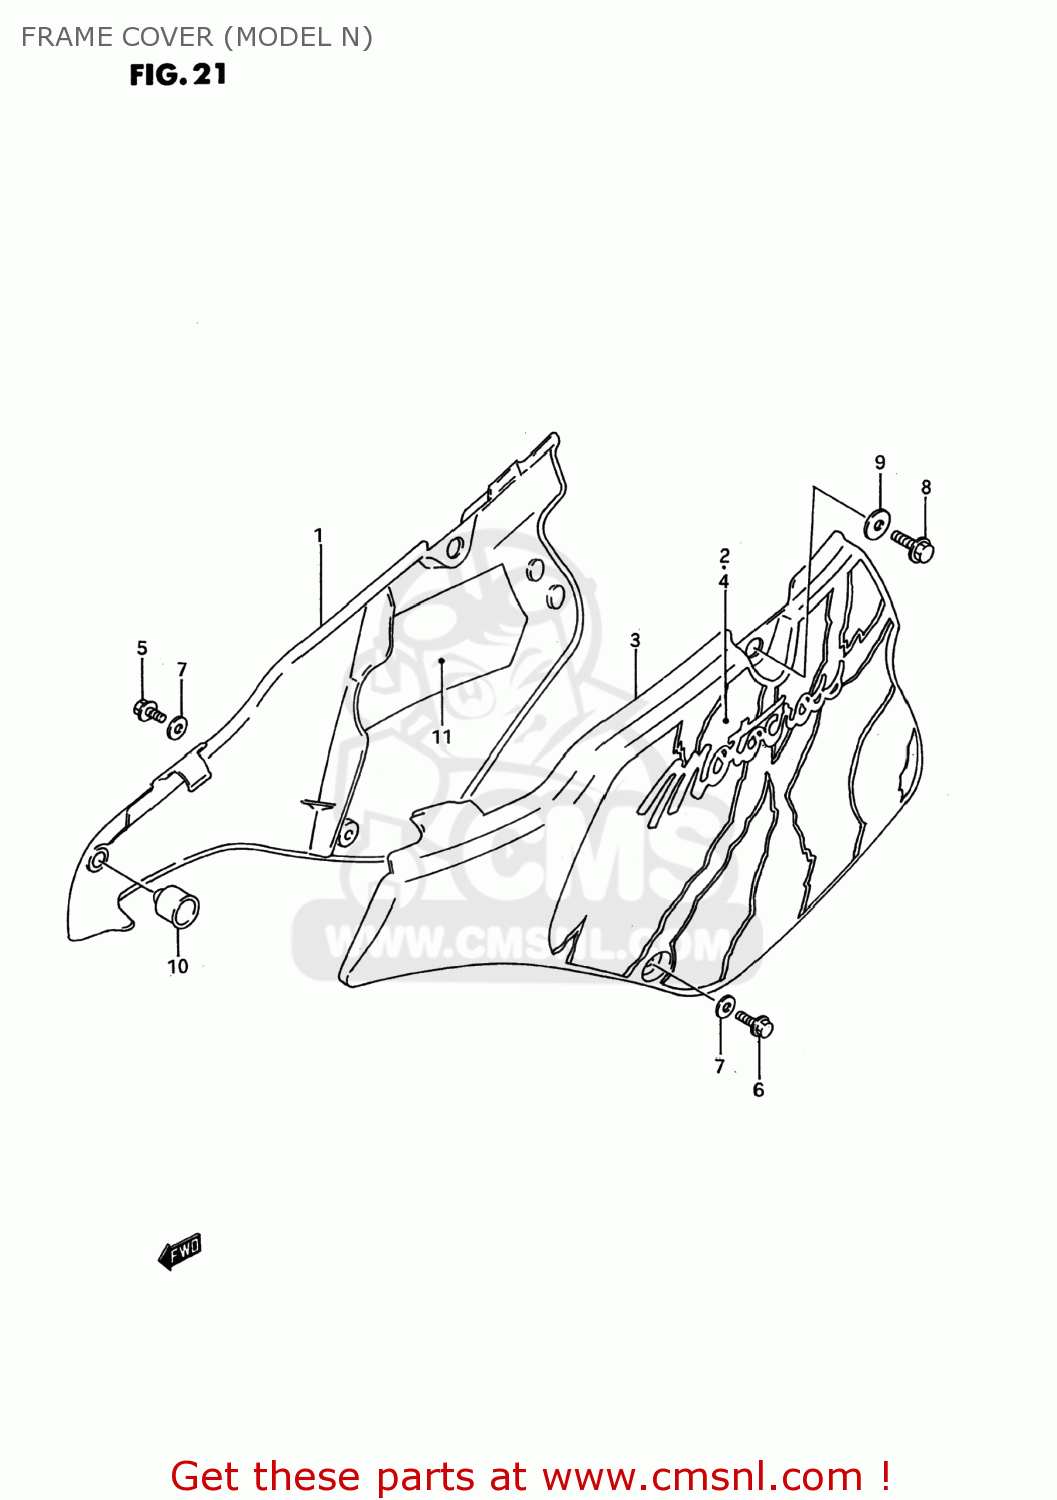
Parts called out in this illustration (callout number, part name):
1	COVER,FRAME,R(WHITE)
2	EMBLEM,FRAME COVER,RIGHT
3	COVER,FRAME,L(WHITE)
4	EMBLEM,FRAME COVER,LEFT
5	BOLT
6	BOLT
7	GASKET(6.5X20X1.5) (NAS)
8	BOLT
9	WASHER
10	CUSHION
11	SHIELD,FRAME COVER,RIGHT
